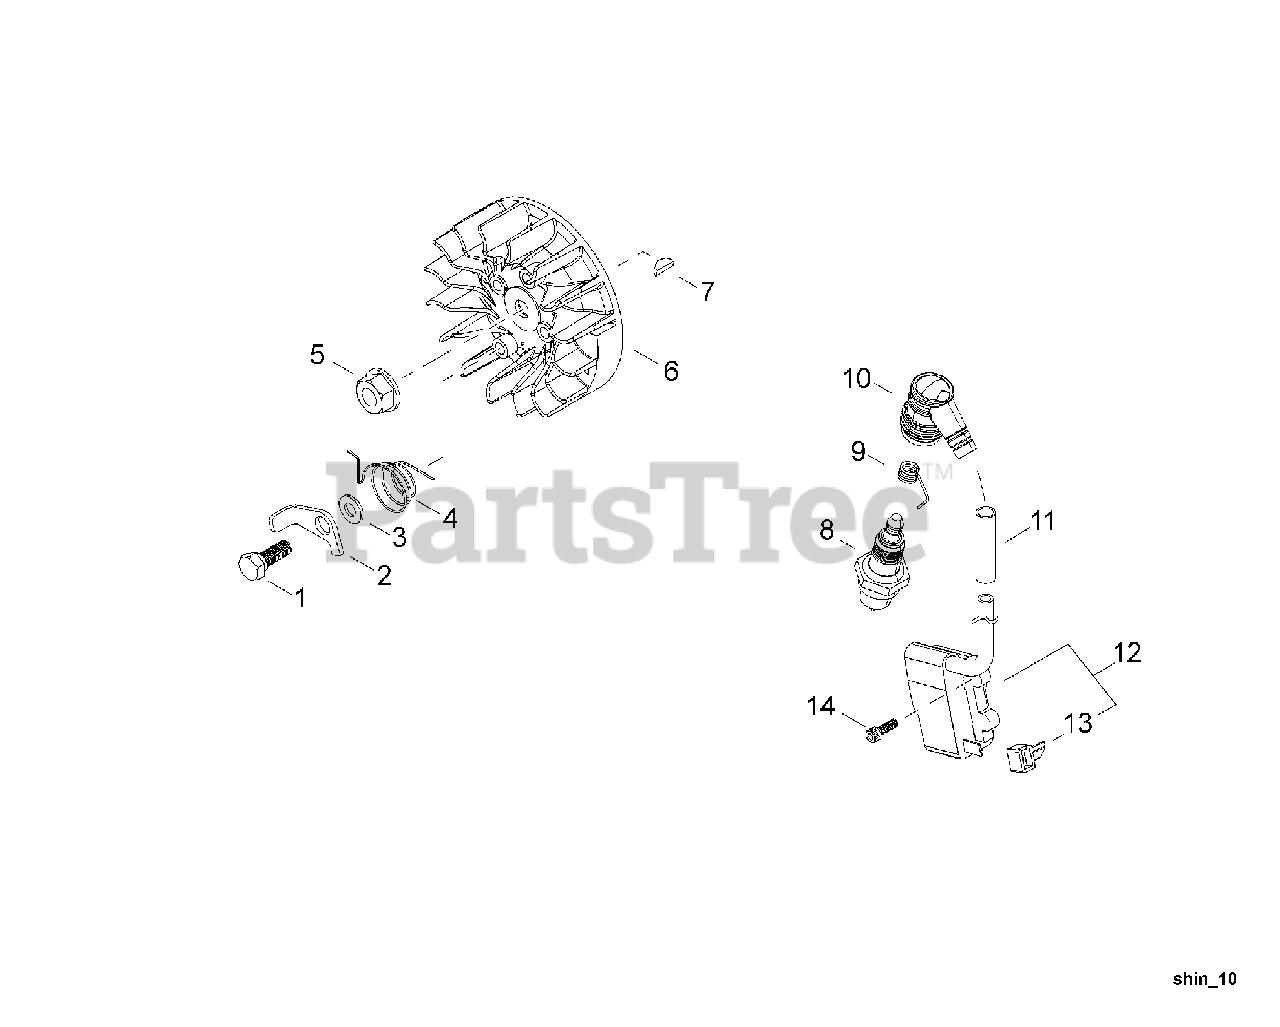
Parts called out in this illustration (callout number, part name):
1	BOLT
2	PAWL, STARTER
3	WASHER
4	SPRING, RETURN
5	NUT - 8
6	FLYWHEEL
7	KEY - 3X10
8	SPARK PLUG -- RCJ-6Y
9	TERMINAL, SPARK PLUG CAP
10	CAP, SPARK PLUG
11	INSULATOR
12	IGNITION COIL ASSY
13	COVER, TERMINAL
14	SCREW - 4X20
